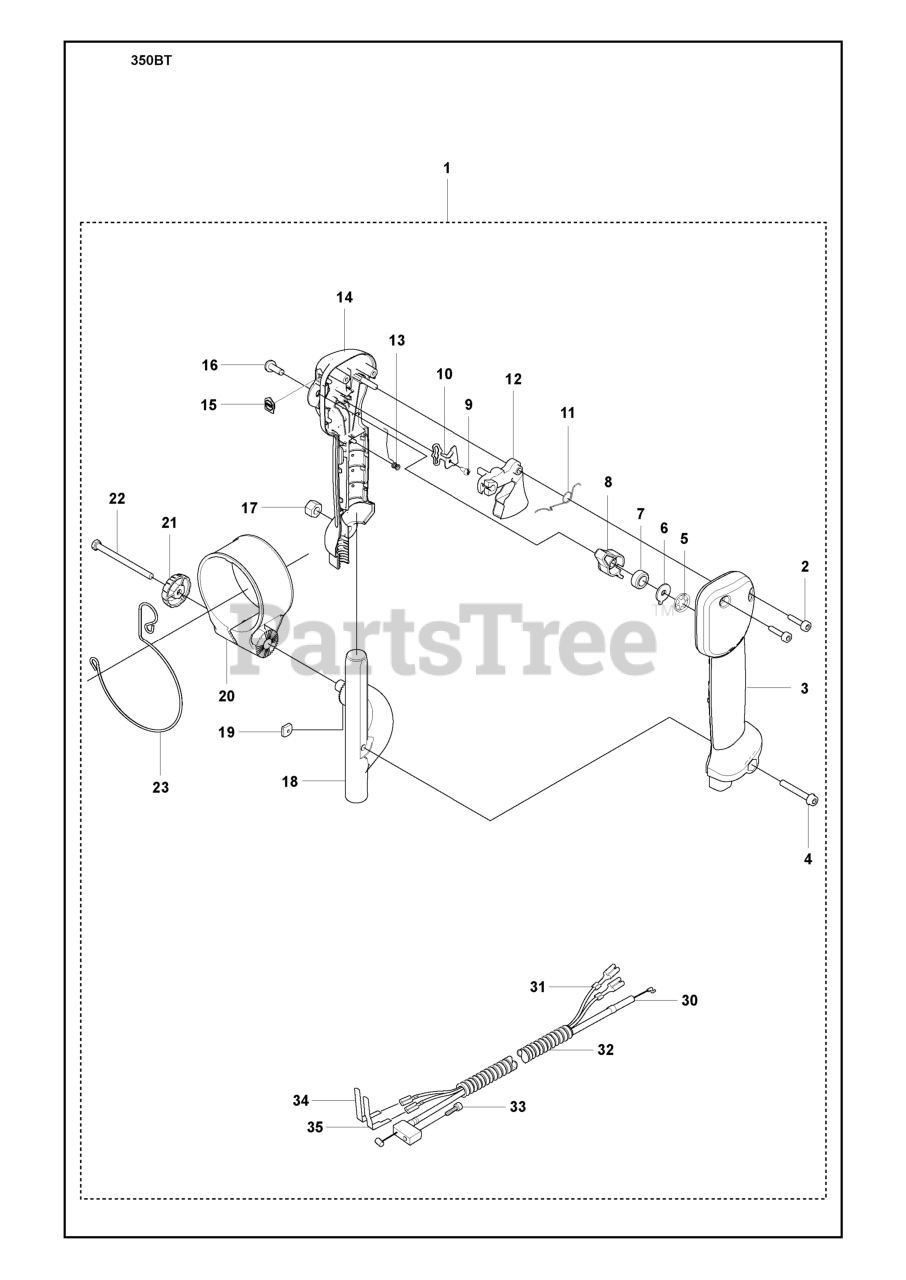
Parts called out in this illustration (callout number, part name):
1	HANDLE ASSY 150BT
3	HANDLE HALF (R)
4	SCREW
7	SPRING RUBBER
8	LEVER STOP
12	TRIGGER 848L5W34C0
14	HANDLE HALF (L)
16	SHAFT PIVOT
18	HOLDER, HANDLE
20	HOLDER TH
21	KNOB
30	CABLE COMP
31	RP CORD
34	CONTACT SPRING
35	CONTACT SPRING
